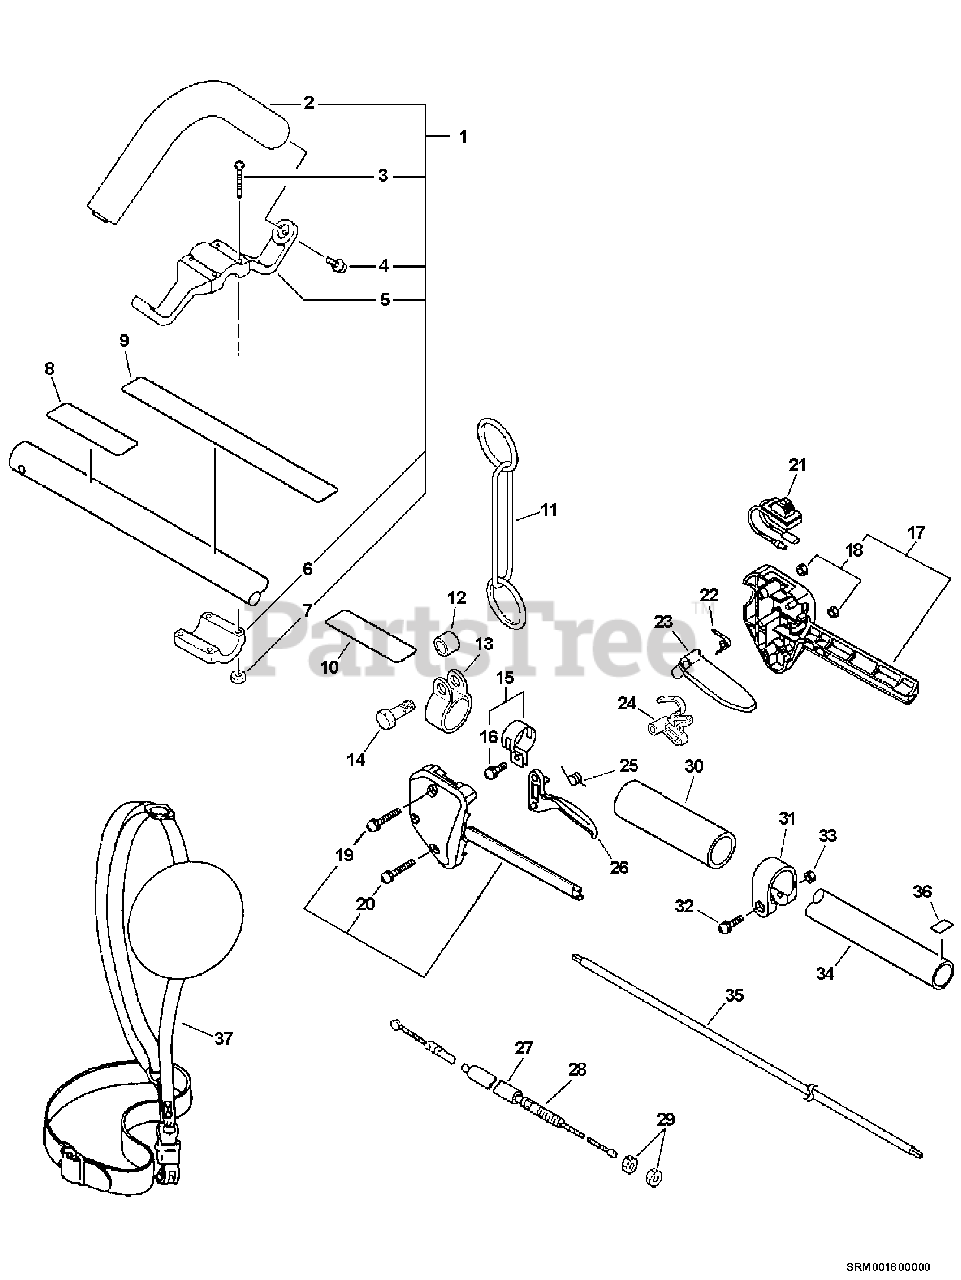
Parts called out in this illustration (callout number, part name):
1	HANDLE ASSY
2	HANDLE - FRONT
3	SCREW - 5X35
4	SCREW - 5X14
5	BRACKET, HANDLE - UPPER
6	BRACKET, HANDLE
8	LABEL - CAUTION -- SPANISH
9	LABEL - CAUTION
10	LABEL - HANDLE LOCATION
14	BOLT - 5X18
15	MAIN PIPE CLAMP KIT
16	SCREW - 5X14
17	THROTTLE BRACKET SET
19	SCREW - 5X35
20	SCREW - 5X25
21	IGNITION SWITCH ASSY
22	SPRING, LOCKOUT LEVER
23	LEVER, TRIGGER LOCKOUT
24	LOCKOUT, THROTTLE
25	SPRING, TRIGGER
26	TRIGGER, THROTTLE
27	TUBE - VINYL
28	CABLE, THROTTLE
30	GRIP, HANDLE
32	SCREW - 5X28
34	PIPE, MAIN
35	DRIVESHAFT - SOLID
36	LABEL - ALIGNMENT
37	SHOULDER STRAP ASSY
